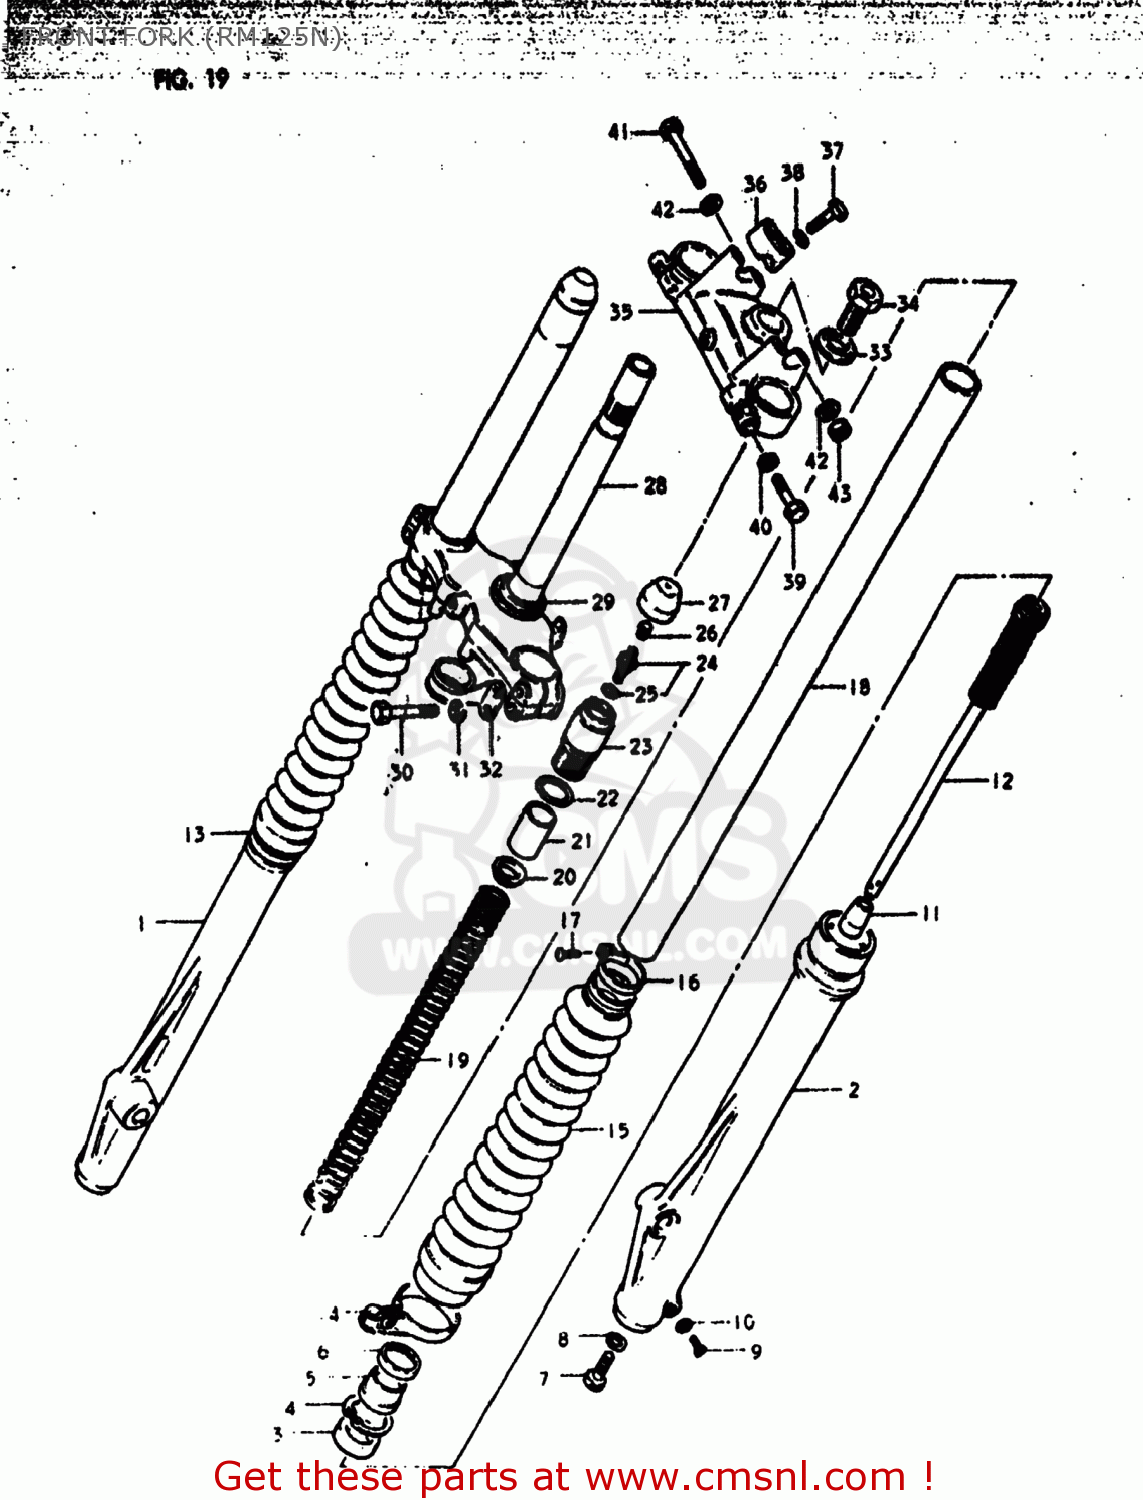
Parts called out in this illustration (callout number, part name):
1	TUBE,OUTER,RIGHT
2	TUBE,OUTER,LEFT
3	SEAL,OIL
4	CIRCLIP,FORK OIL SEAL
5	DUST SEAL,FRONT FORK
6	CASE,DUST SEAL FRONT FORK
7	BOLT,CYLINDER
8	GASKET,CYLINDER (NAS)
9	SCREW
10	GASKET,DRAIN,PLUG (NAS)
11	PIECE,OIL LOCK
12	CYLINDER,FRONT FORK
13	BAND,FRONT FORK COVER BOOT
14	BAND,FRONT FORK COVER BOOT
15	BOOT
16	BAND,BOOT
17	SCREW
18	TUBE,FORK,INNER
19	SPRING
20	GUIDE
21	COLLAR,SPRING
22	O RING
23	CAP,FORK INNER TUBE
24	VALVE
25	O RING
26	CAP,VALVE AIR
27	CAP
28	STEM,STEERING
29	RACE,STEERING,OUTER,UPPER
30	BOLT 8X45
31	LOCK WASHER
32	GUIDE,CABLE
33	WASHER
34	BOLT
35	HEAD,STEERING STEM
36	HOLDER,HANDLEBAR
37	BOLT
38	LOCK WASHER
39	BOLT
40	LOCK WASHER
41	BOLT 8X50
42	WASHER
43	NUT
